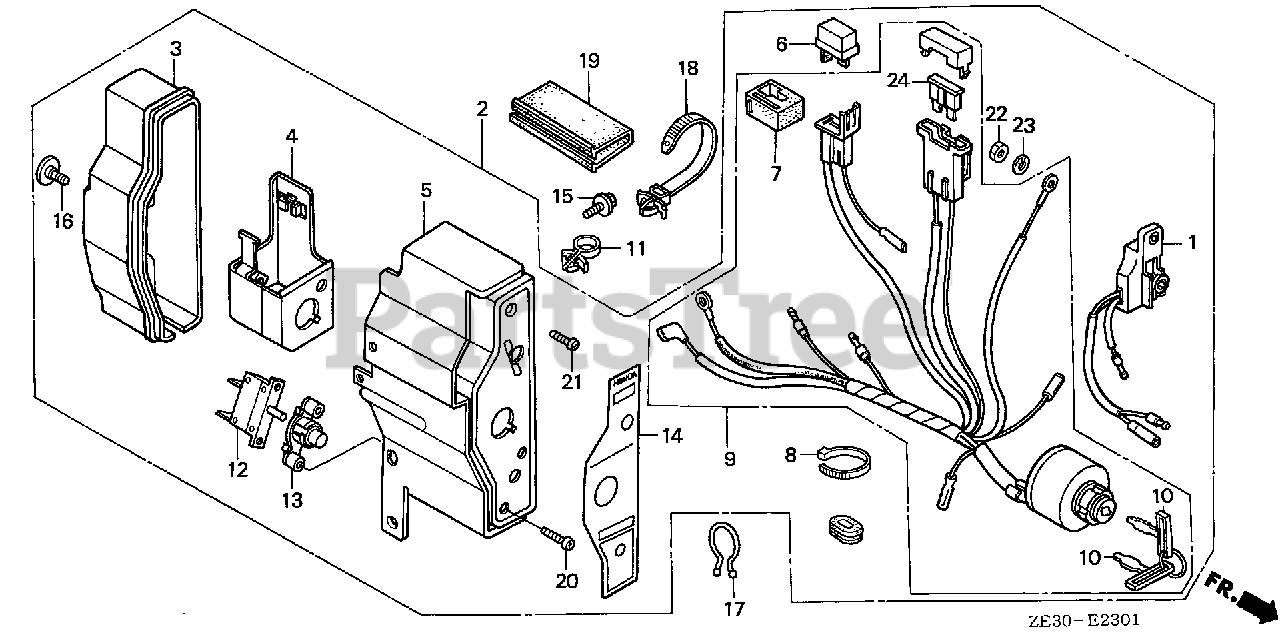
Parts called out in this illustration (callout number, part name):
1	ALERT UNIT, OIL (NOT AVAILABLE)
2	BOX ASSY., CONTROL (EXTERNAL-ALERT) (NOT AVAILABLE)
2	BOX ASSY., CONTROL (EXTERNAL-ALART-3A) (NOT AVAILABLE)
3	CASE, CONTROL
4	BRACKET, CASE MOUNTING
5	PANEL, CONTROL *R280* (POWER RED)
6	RECTIFIER ASSY., SILICON (SHINDENGEN)
7	SUSPENSION, CONNECTOR
8	BAND
9	SWITCH ASSY., COMBINATION
9	SWITCH ASSY., COMBINATION (3A-CHARGE)
10	KEY (HONDALOCK)
11	HOLDER, STOP SWITCH WIRE
12	PROTECTOR, CIRCUIT (1.0A)
12	PROTECTOR, CIRCUIT (3.5A)
13	LENS ASSY., PROTECTOR
14	PANEL, CONTROL BOX (EXTERNAL-ALERT) (NOT AVAILABLE)
15	BOLT, FLANGE (6X12) (CT200)
16	SCREW, SPECIAL (6X12)
17	CLIP, PURSE LOCK
18	STRAP, CABLE (118MM) (BLACK)
19	TUBE, FASTENER (30MM)
20	SCREW, PAN (3X12)
21	SCREW, PAN (4X12)
22	NUT, HEX. (4MM) (SOURCE: VINTAGE PARTS INC.)
23	WASHER, SPRING (4MM)
24	FUSE, BLADE (5A)
24	FUSE, BLADE (15A)
